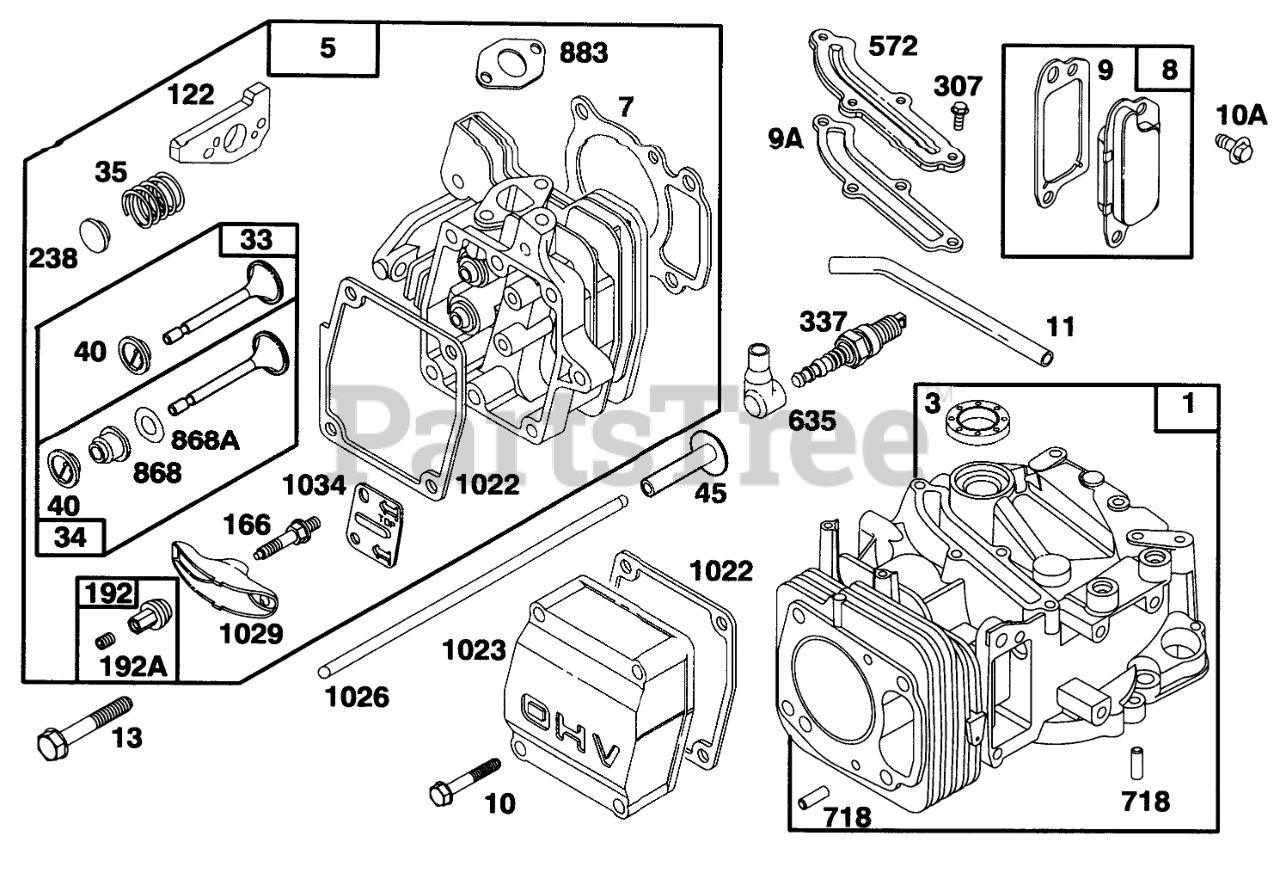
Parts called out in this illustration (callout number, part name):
1	CYLINDER ASSEMBLY
3	SEAL - OIL
5	CYLINDER HEAD
7	CYLINDER HEAD GASKET
8	Breather Assy
9	BREATHER GASKET
9A	GASKET-BREATHER
10	HEX HEAD SCREW
10A	HEX HEAD SCREW
11	TUBE - BREATHER
13	CYLINDER HEAD SCREW
33	EXHAUST VALVE
34	INTAKE VALVE
35	VALVE SPRING
40	SPRING RETAINER
45	VALVE TAPPET
122	ADAPTER ASSEMBLY
166	ROCKER ARM STUD
192	NUT - HEX SPECIAL
192A	SCREW SET
238	VALVE CAP
307	SCREW - SEM
337	PLUG-SPARK
572	BAFFLE - CYCLINDER
635	SPARK PLUG ELBOW
718	DOWEL - SLEEVE
868	SealAssy-Valve
868A	Seal-Valve
883	EXHAUST GASKET
1022	ROCKER COVER GASKET
1023	COVER - VALVE
1026	PUSH ROD
1029	ROCKER ARM
1034	PUSH ROD GUIDE
